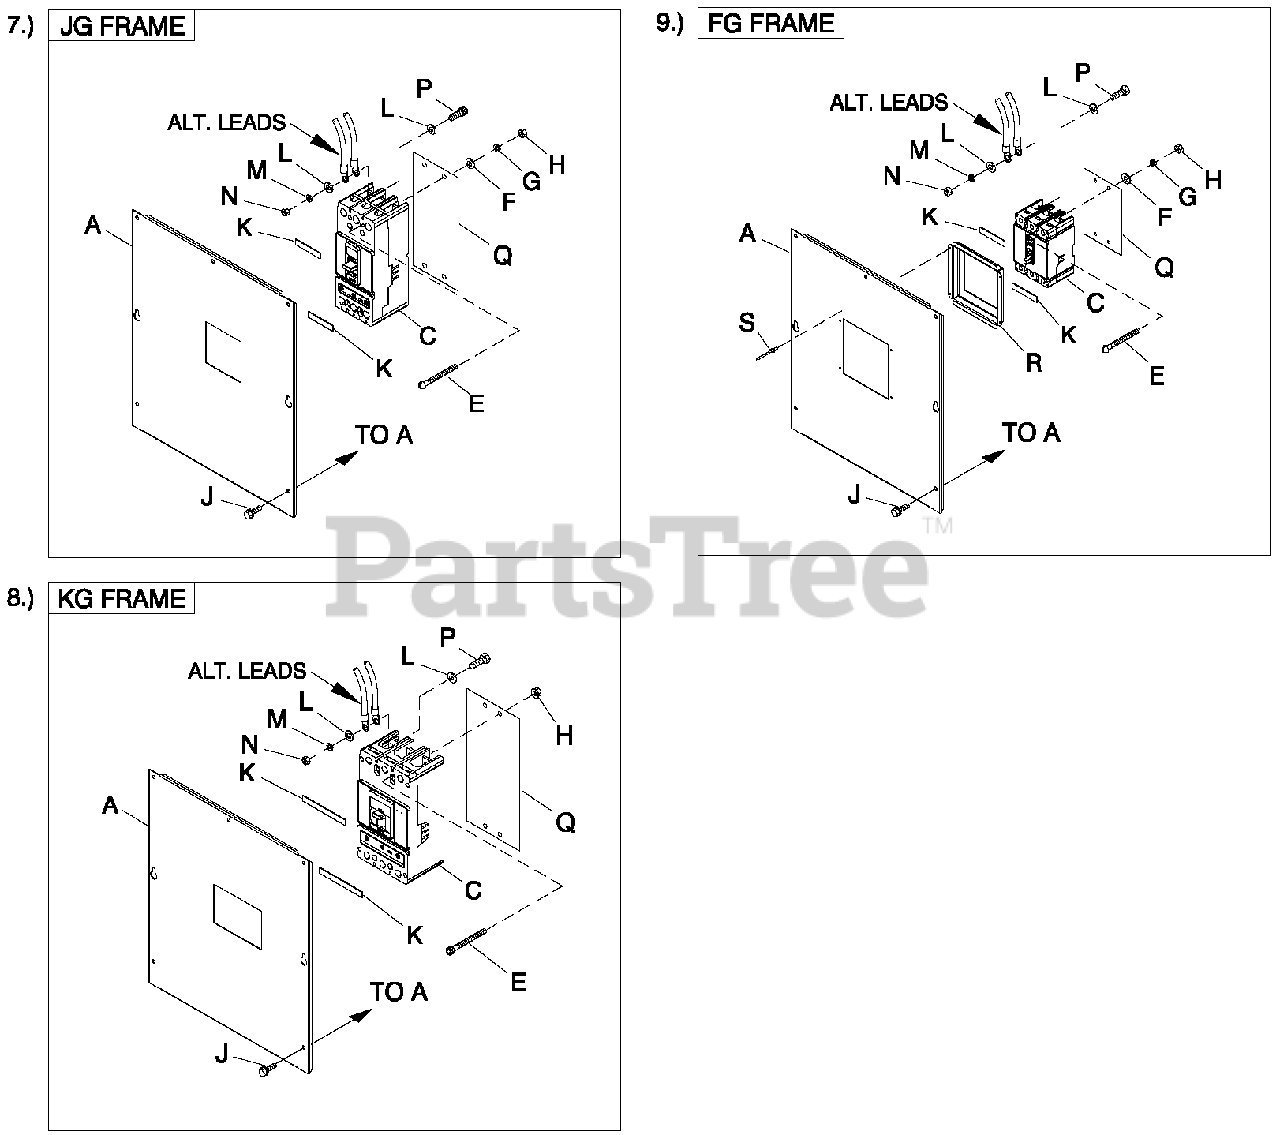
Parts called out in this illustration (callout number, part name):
7	UL CIRCUIT BREAKER (JG)
8	UL CIRCUIT BREAKER (KG)
9	UL CIRCUIT BREAKER (3P FG)
A	COVER CB E JG FRAME C3
C	CB 0250 3P 600V E JG LL
E	SCREW RHM 1/4-20 X 3
F	WASHER FLAT 1/4-M6 ZINC
G	WASHER LOCK M6-1/4
H	NUT HEX 1/4-20 STEEL
J	SCREW THF M6-1 X 16 N WA Z/JS
K	TAPE ELEC 1/2 FOAM
L	WASHER FLAT 5/16-M8 ZINC
M	WASHER LOCK M8-5/16
N	NUT HEX M8-1.25 G8 CLEAR ZINC
P	SCREW HHC M8-1.25X 25 C8.8
Q	INSULATOR CB E 3P JG
A	COVER CB E KG FRAME C3
C	CB 0300 3P 600V E KG LL
E	SCREW SHC M6-1.0X50 C8.8
H	NUT FLANGE M6-1.0 NYLOK
Q	INSULATOR CB E 3P KG
A	COVER CB G 225AF C3
C	CB 0125 3P 480VE FG LL
E	SCREW PPHM #8-32 X 1-3/4 ZINC
F	WASHER FLAT #8 ZINC
G	WASHER LOCK #8-M4
H	NUT HEX #8-32 STEEL
L	WASHER FLAT #10 ZINC
M	WASHER LOCK M5
N	NUT HEX M5-0.8 G8 CLEAR ZINC
P	SCREW HHC M5-0.8X 20 G8.8
Q	INSULATOR CB 3P E TYPE CC/FG
R	COVER CB DISH 3P E FD
S	RIVET POP.125 X .275 SS
